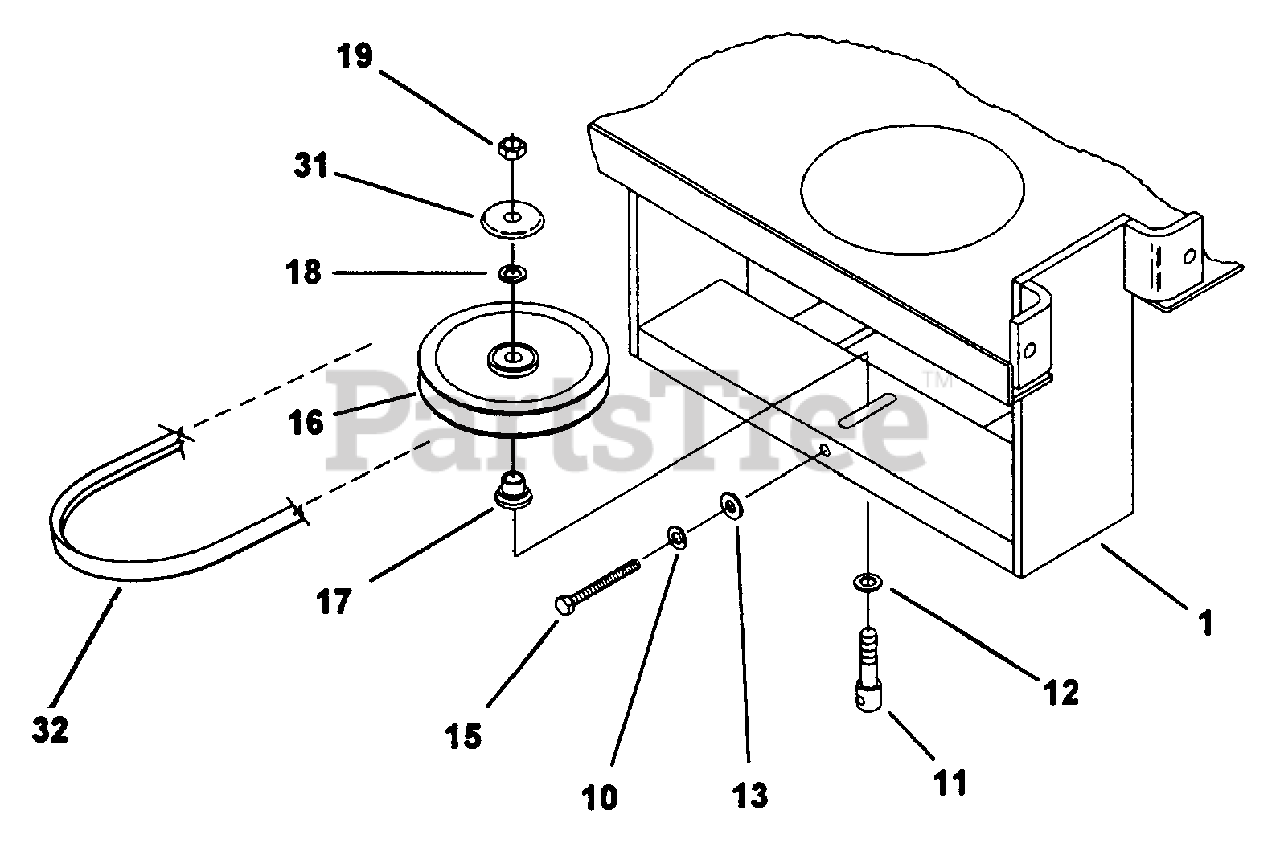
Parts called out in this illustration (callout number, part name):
1	MOTOR MOUNT WELDMENT
10	LOCKWASHER, 5/16" SPLIT SPRING
11	STUD, ADJUSTABLE
12	WASHER, FLAT STD. 1/2"
13	WASHER, FLAT STD. 5/16"
15	CAPSCREW, 5/16-18 X 3" GR.2 FULL THRD.
16	IDLER PULLEY ASSEMBLY
17	IDLER STAND, POWDER METAL
18	WASHER, 1/2" NOM. TYPE B NARROW
19	LOCKNUT, 1/2-13, NYLOC
31	WASHER, BEARING CAP
32	BELT, A-70 KEVLAR, MAIN DRIVE BELT
